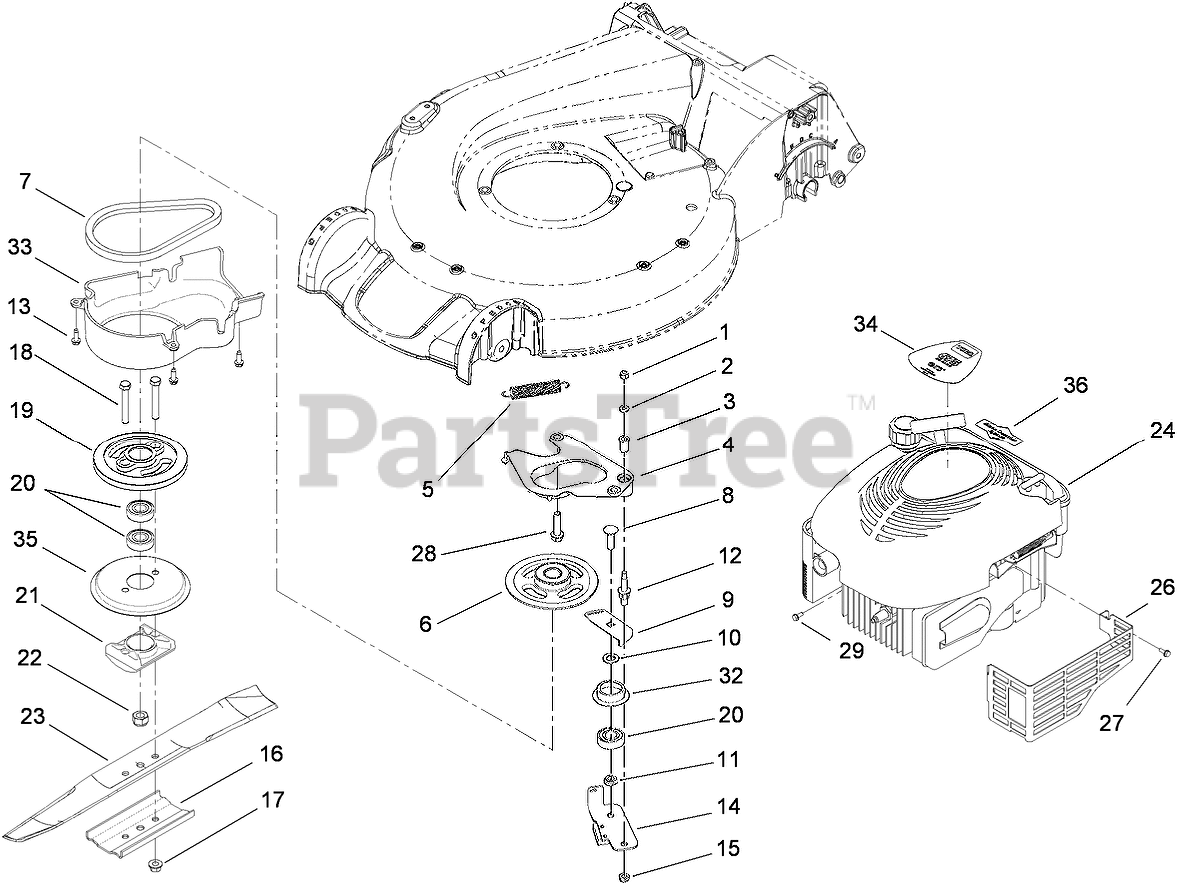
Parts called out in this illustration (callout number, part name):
1	NUT-LOCK, NI
2	WASHER-FLAT
3	BUSHING
4	PLATE-ANCHOR
5	SPRING-TENSION, BRAKE
6	PULLEY
7	BELT
8	BOLT-CARR
9	PLATE-GUIDE
10	WASHER-PLAIN
11	SPACER-BEARING
12	BOLT-SHOULDER
13	SCREW-HWHTF
14	BRAKE ARM ASM
16	SUPPORT-BLADE
17	NUT-LOCK
18	SCREW-HH
19	DRUM
20	BEARING-BALL
21	SUPPORT-BLADE
22	NUT-HEX
23	BLADE-RECYCLING
26	SHIELD-MUFFLER
27	SCREW-TAPTITE
28	SCREW-HWH
29	SCREW-HWH
32	RETAINER-BELT
34	DECAL-ENGINE
35	DISC
36	DECAL-RECOIL
